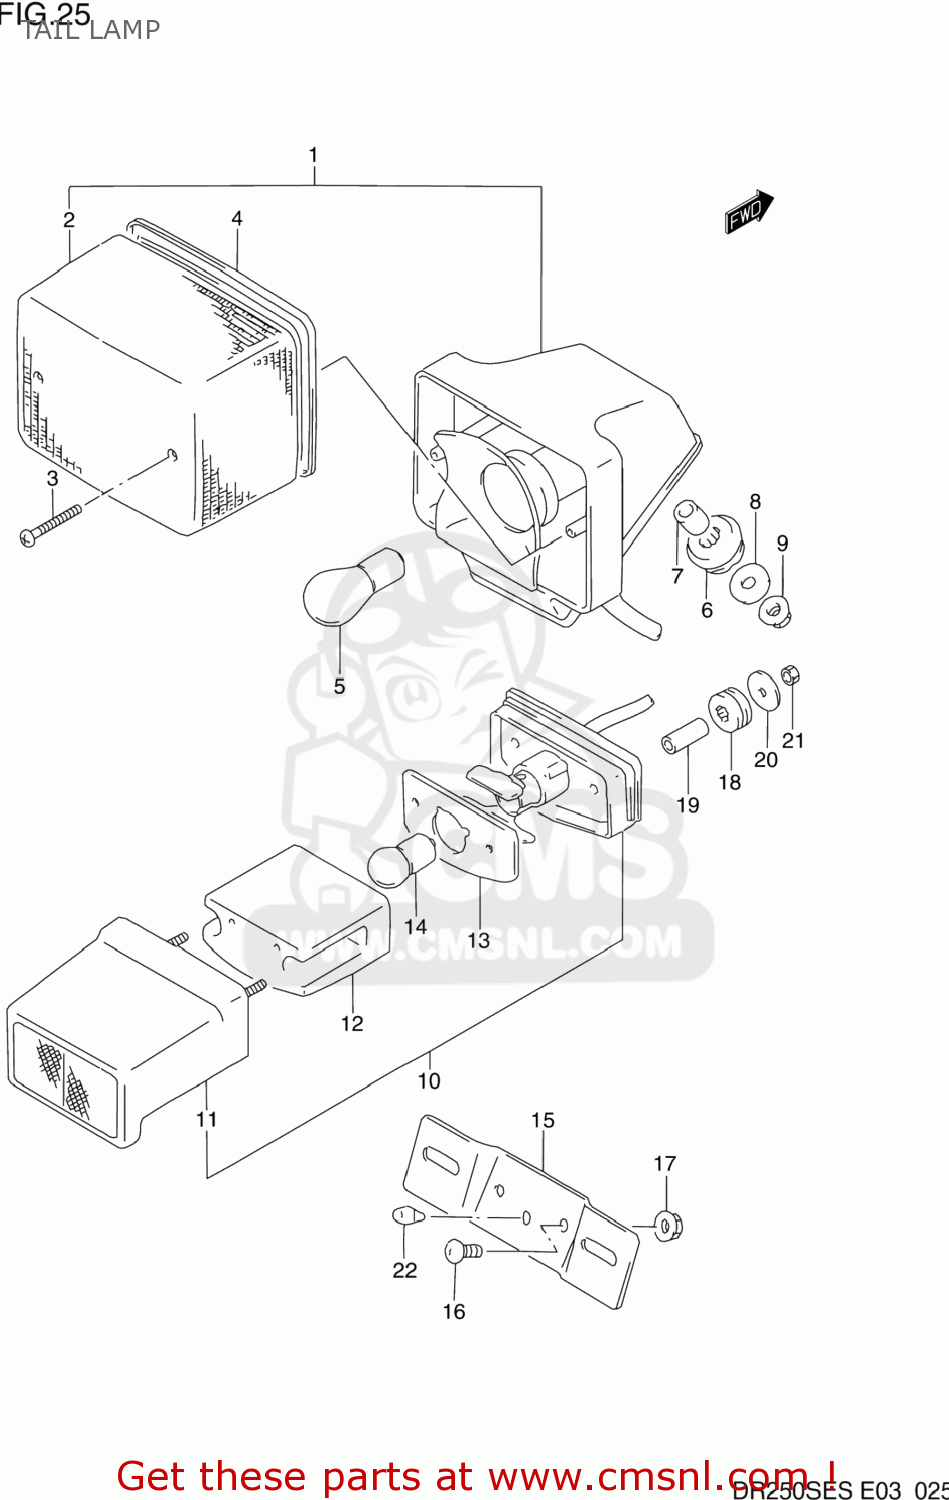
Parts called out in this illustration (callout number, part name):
1	LAMP ASSY,RR COMBINATION
2	LENS,TAIL LAMP
3	SCREW(4X45)
4	GASKET,LENS (NAS)
5	BULB(12V21/5W)
6	CUSHION
7	SPACER (6.1X9X9)
8	WASHER,COVER,FRONT
9	NUT
10	LAMP ASSY,LICENSE
11	REFLECTOR/COVER
12	LENS
13	GASKET,LICENSE LAMP (NAS)
14	BULB
15	BRACKET,LICENSE PLATE
16	SCREW
17	NUT
18	CUSHION
19	SPACER,LICENSE LAMP
20	WASHER(5.5X20X1.2)
21	NUT
22	CUSHION
